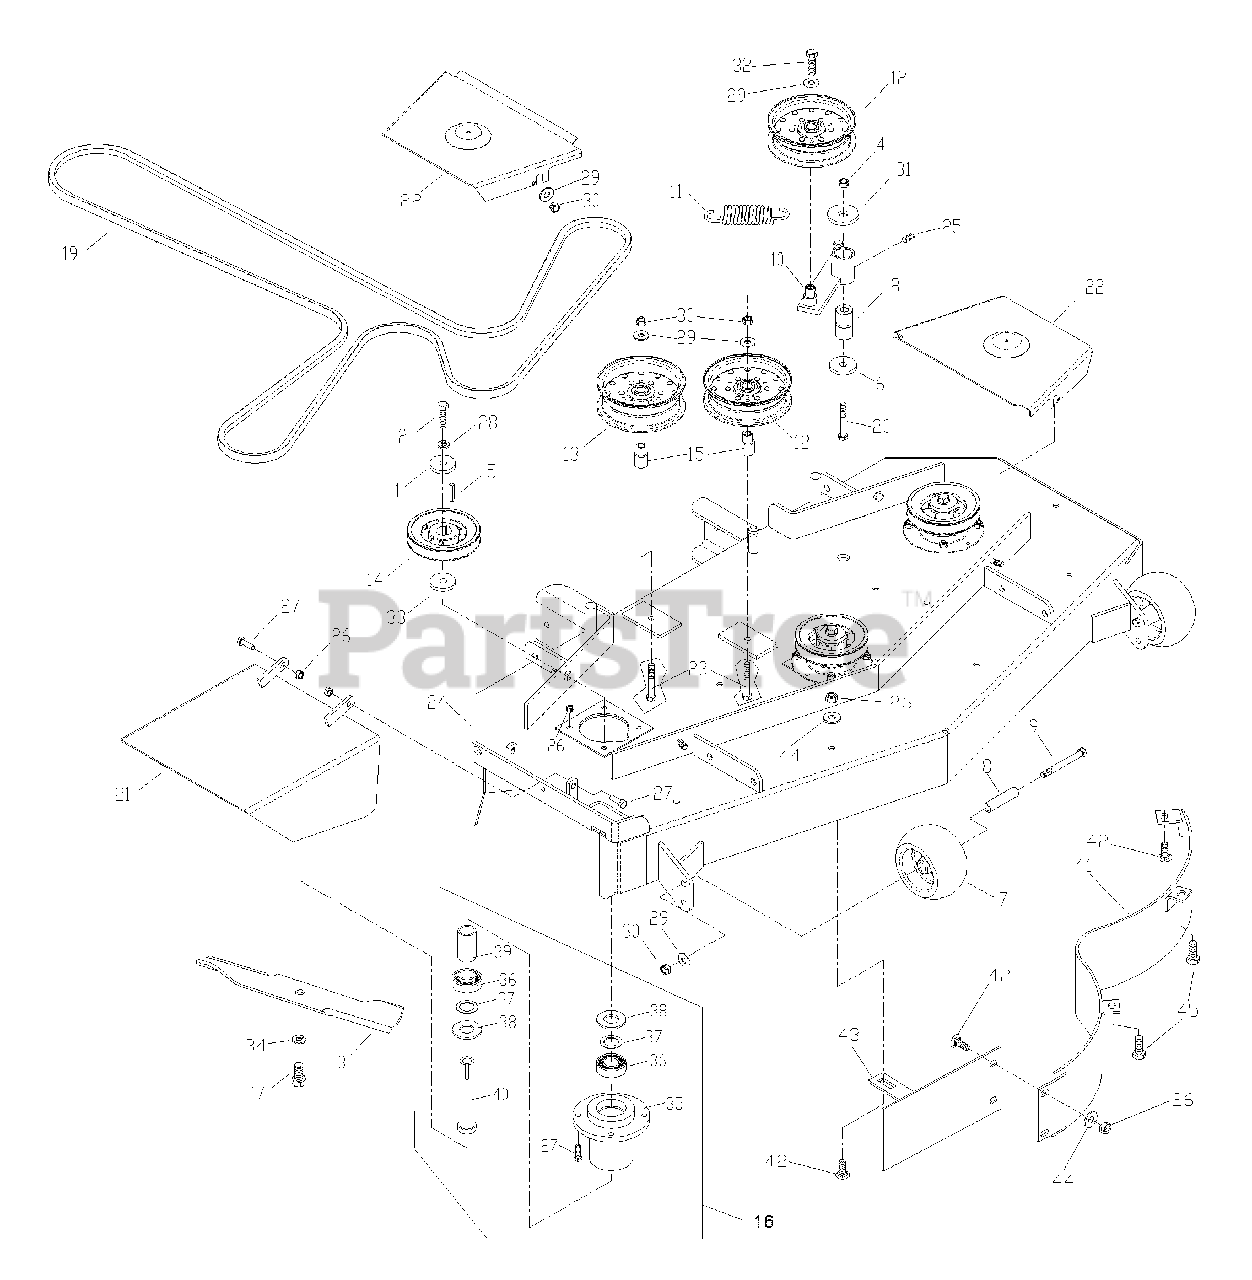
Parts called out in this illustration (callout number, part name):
1	HEAVY WASHER
2	HCS 7/16 X 1.500
3	BLADE 16.250
4	NUT 1/2 NYLOC
5	KEY 1/4 X 1.125
6	SUPPORT WASHER
7	ANTI-SCALP ROLLER
9	HCS 3/8 X 3.500
12	IDLER PULLEY
13	IDLER PULLEY
15	IDLER BUSHING
16	COMPLETE HOUSING
17	HCS 5/16 X 1.250
18	PIVOT BUSHING
19	BELT
20	HCS 1/2 X 3.250
21	DEFLECTOR CHUTE
22	BELT SHIELD
23	HCS 3/8 X 2.500
24	DECK W/DECALS
25	ZERK
26	NUT 5/16 CTR. LOCK
27	HCS 5/16 X 1.000
28	WASHER 7/16 LOCK
29	WASHER 3/8 FLAT
30	NUT 3/8 CTR. LOCK
31	WASHER 1/2 FLAT
32	HCS 3/8 X 1.00 SERR. HD.
33	MACH. BUSHING
34	WASHER 5/8 LOCK
36	BEARING
37	MACH. BUSHING
38	MACH. BUSHING
41	MAIN BAFFLE
42	RHSNB 5/16 X .625
43	CENTER BAFFLE
44	WASHER 5/16 FLAT
45	HCS 5/16 X .750
